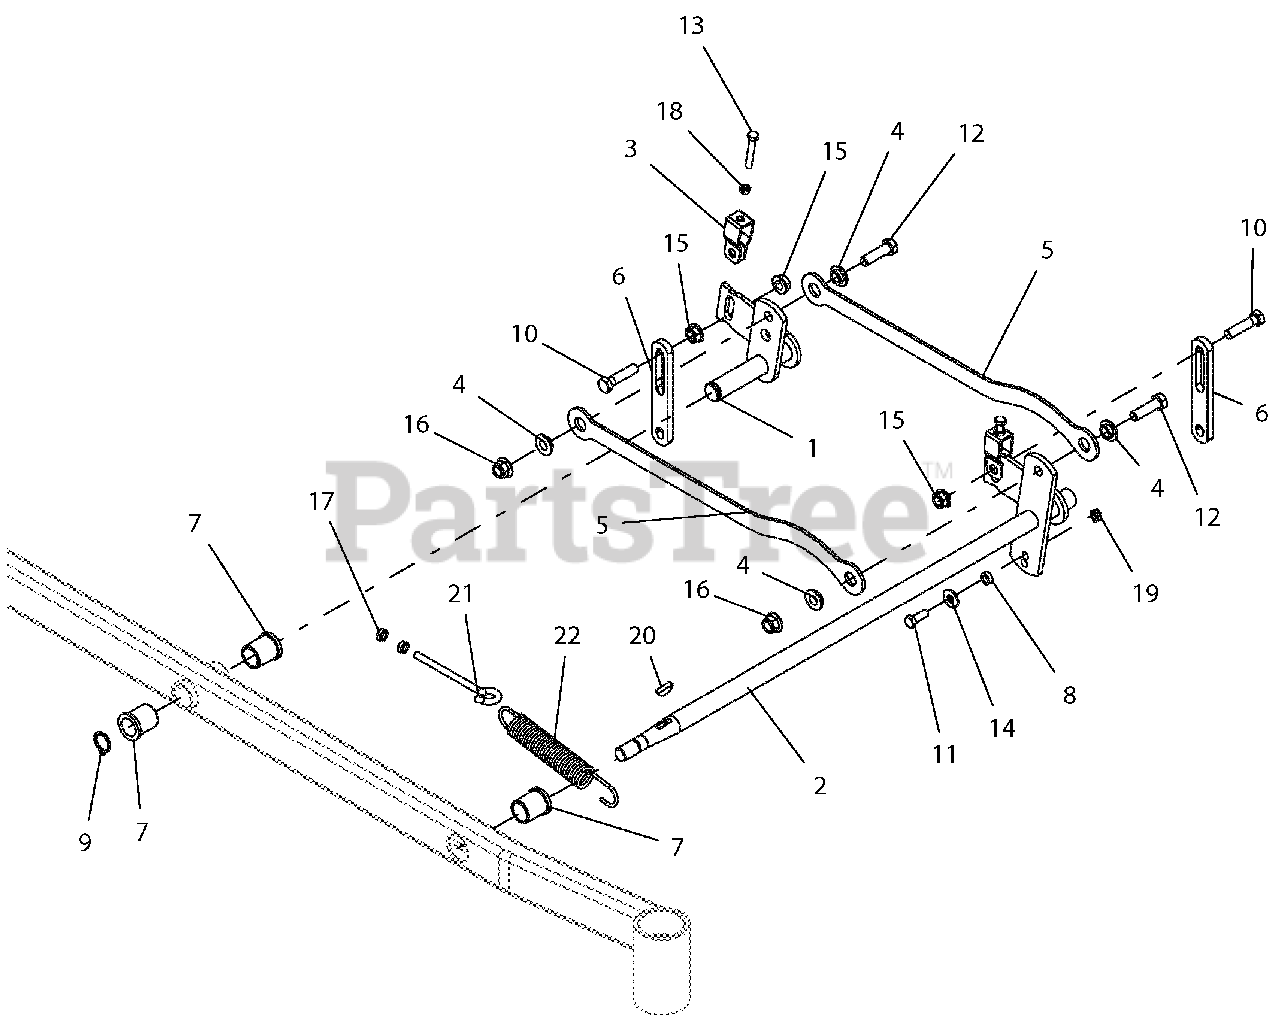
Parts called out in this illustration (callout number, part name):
1	WLDMT, REAR LH DECK LIFT
2	WLDMT, FRONT LH DECK LIFT ARM-BLACK
3	BRKT, DECK LEVELING
4	BSHG, FLANGE .515X.750X.31X1.12
5	LINK, LIFT - BLK
6	LINK, DECK LIFT - LONG
7	BSHG-FLG 1.00X1.25X1.5X1.5
8	BSHG, SLV .377X.624X.235
9	RG-RTNG-EXT 1.00X.078
10	BLT, HEX M12-1.75X50 CLS8.8 YZ
11	BLT-HEX .38-16X1.00 GR5 YWZC
12	BLT-HEX .50-13X1.75 GR5 YWZC
13	BLT-HEX .31-18X2.00 FTH GR5 YWZC
14	WSHR-FL-STL.438X1.00X.083 YWZC
15	NUT, SPLK -FLG M12-1.75 YZ
16	NUT-LK-NYL-FLG .50-13 YWZC
17	NUT, JAM .375-16 YWZC
18	NUT, JAM .312-18 YWZC
19	@NUT-LK-CTR-JAM .375-16 YWZC
20	KEY, WDRF .25 X 1.00 HRD #15
21	BOLT, EYE .38-16X6.00 .62 DIA
22	SPRG, TENSION .162 X 1.250 X 8.250
